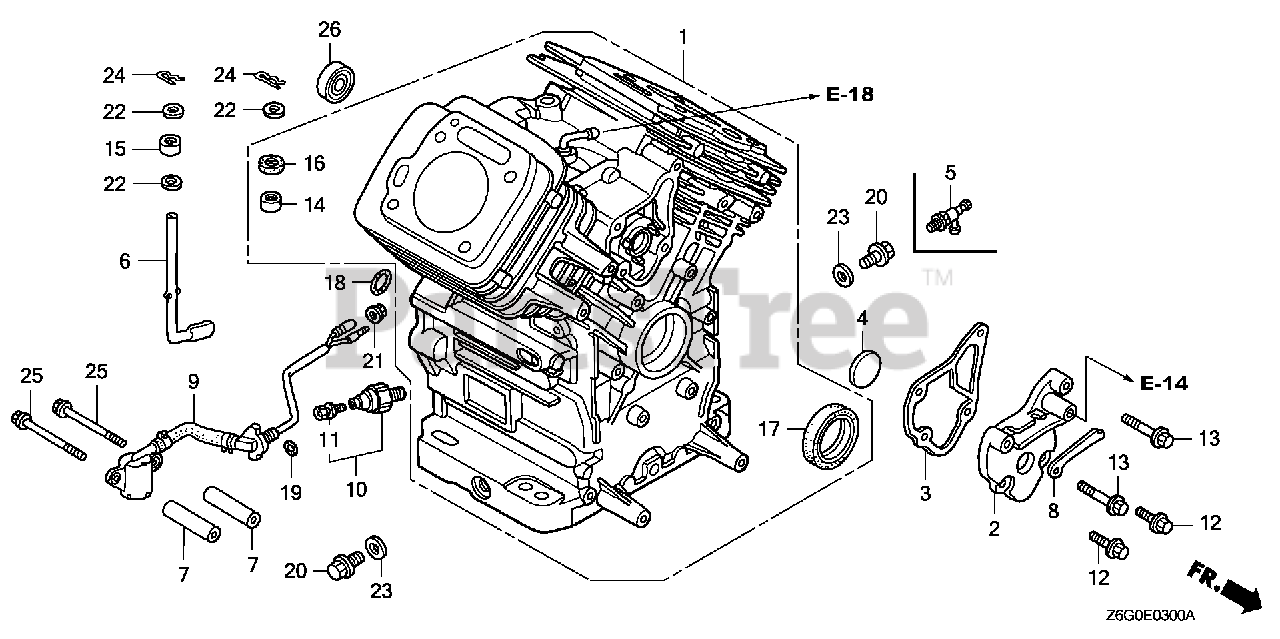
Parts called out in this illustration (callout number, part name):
1	CYLINDER ASSY.
2	COVER, BREATHER
3	GASKET, BREATHER COVER
4	VALVE, BREATHER
5	VALVE, DRAIN (14X1.5)
6	SHAFT, GOVERNOR ARM
7	COLLAR, FILTER SETTING
8	CLAMP, WIRE
9	SWITCH ASSY., OIL LEVEL
10	SWITCH ASSY., OIL PRESSURE
11	SCREW-WASHER (4X8)
12	BOLT, FLANGE (6X16) (CT200)
13	BOLT, FLANGE (6X32) (CT200)
14	BEARING, NEEDLE (8X12.7X11.1)
15	BEARING, NEEDLE (8X12X10)
16	OIL SEAL (8X14X5)
17	OIL SEAL (38X58X9)
18	O-RING (13X3.0)
19	O-RING (14MM) (ARAI)
19	O-RING (14MM) (NOK)
20	BOLT, DRAIN PLUG (14MM)
21	NUT, FLANGE (10MM)
22	WASHER, PLAIN (8MM)
23	WASHER, DRAIN PLUG (14MM)
24	PIN, LOCK (8MM)
25	BOLT, FLANGE (6X75)
26	BEARING, RADIAL BALL (6003)
